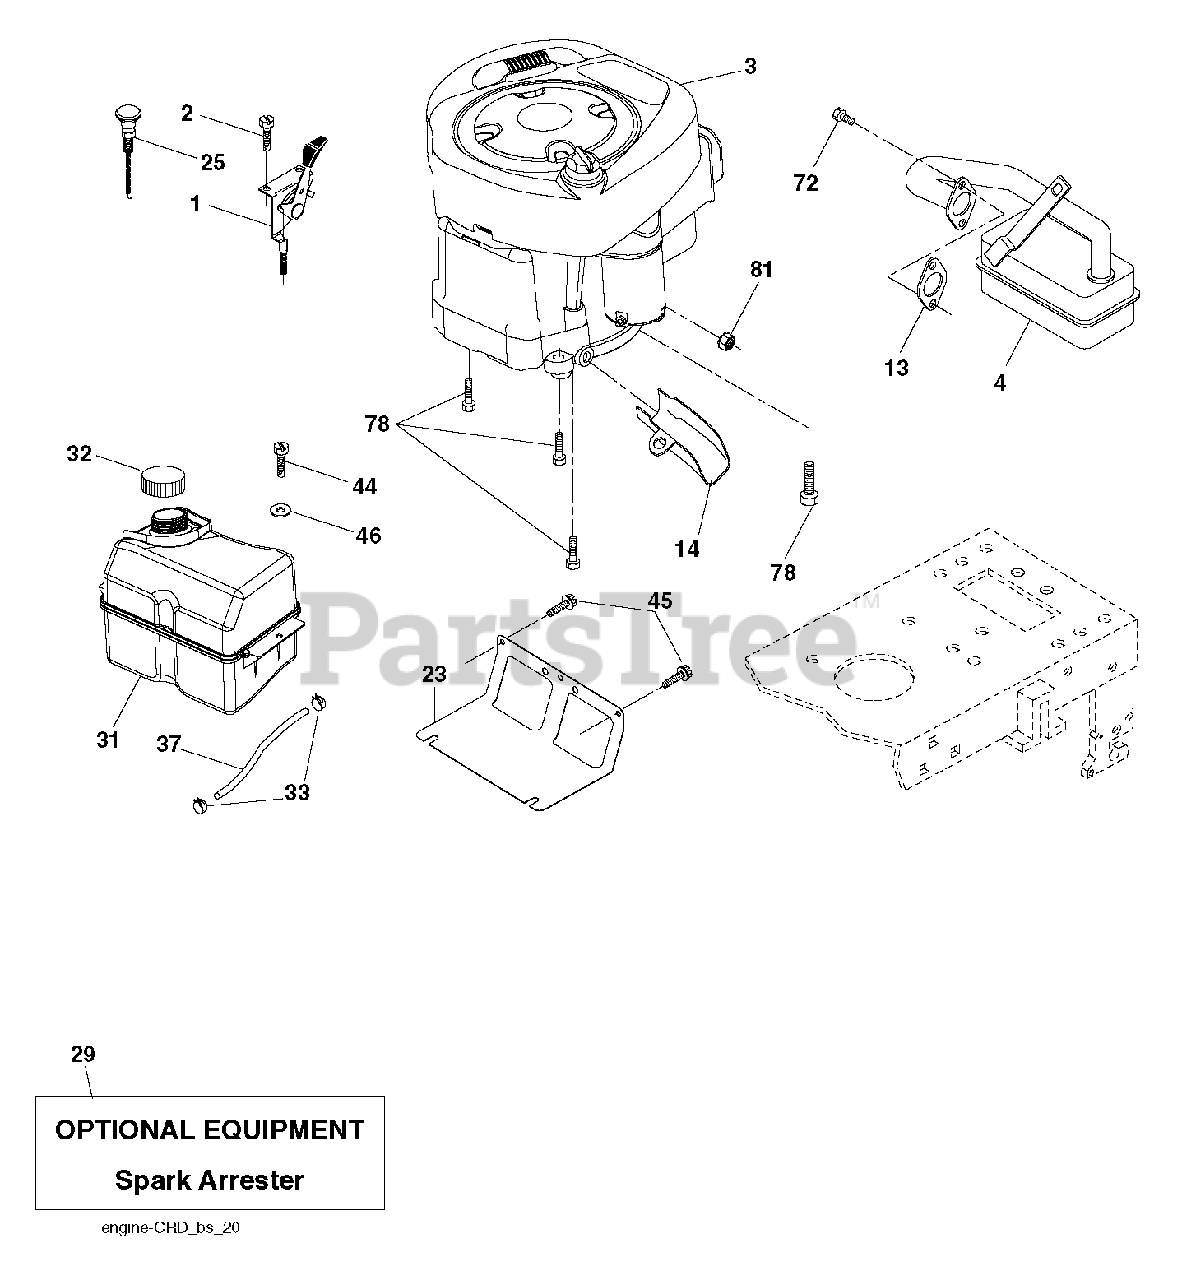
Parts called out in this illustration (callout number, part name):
1	CONTROL TH/CH FLAG
2	SCREW
13	REPL BY 532 27 22-93
14	EXTENSION DRAIN OIL
23	SHEILD.BROWNING.DBR.GUARD
25	KNOB.ERGO.EXTENDED.RED (1 2)
29	ARRESTER SPARK (OPTIONAL)
32	CAP ASM.FUEL.2.25"FR.
44	SCREW HEXWSHR 1/4-20X3/4
45	SCREW, 3/8-16X3/4
72	SCREW.SOCKET HD.5/16-1
81	NUT
